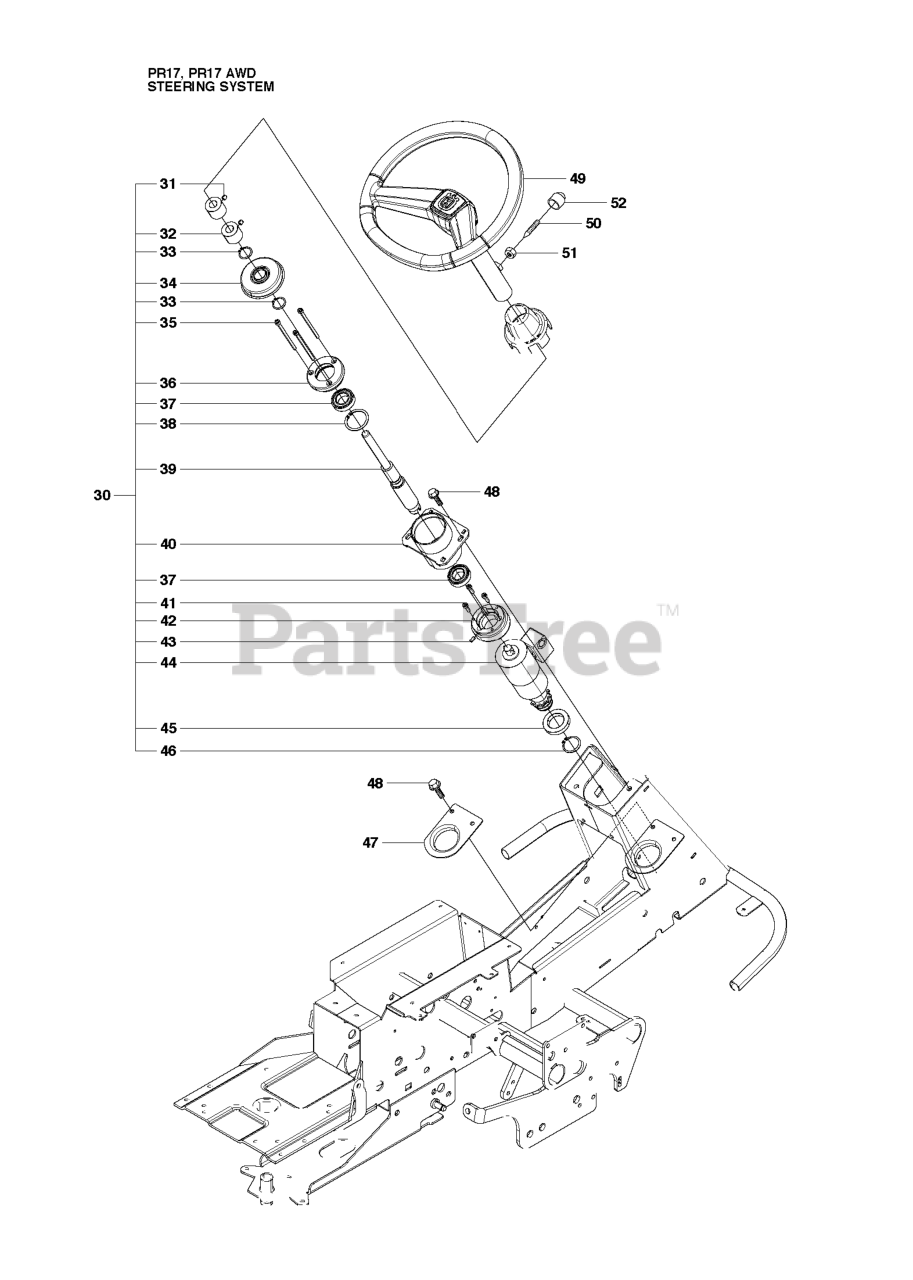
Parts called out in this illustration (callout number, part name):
32	SPACER
33	RETAINING RING SGA 25
35	SCREW IHSCM.
37	Ball Bearing 6005-2rs
38	CIRCLIP SGH 47
41	SCREW MC6S 6X20
43	SPRING PIN
44	COMFORT STEERING
51	NUT
52	PROTECTIVE COVER
